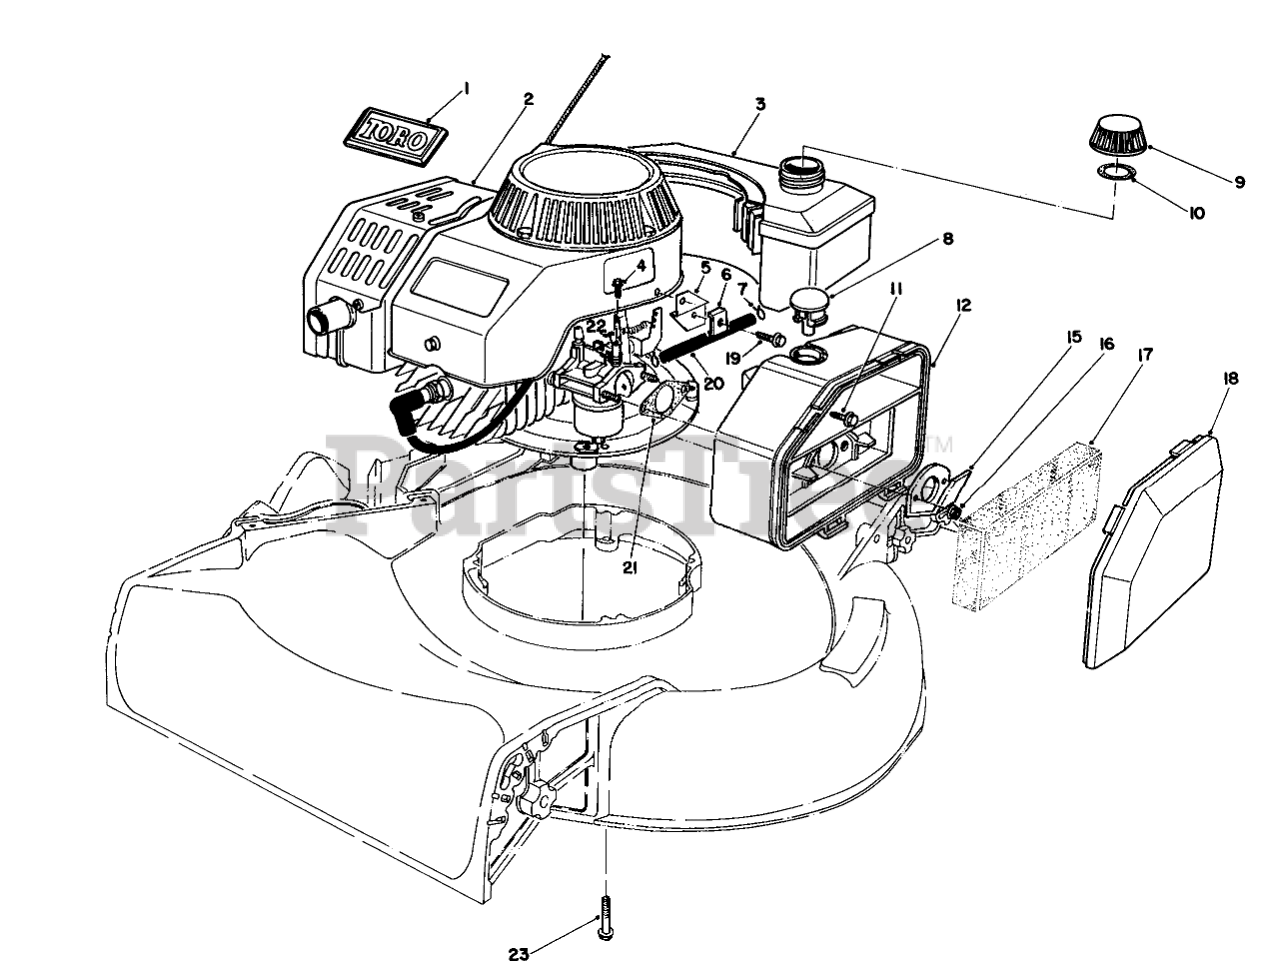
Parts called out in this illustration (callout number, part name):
1	TORO LOGO PLT
2	Engine (Incl. Ref. #1)
3	Fuel Tank Assembly
4	TAPPING SCREW
5	Carrier-Cable
6	CLAMP-CABLE
7	CLAMP-HOSE
8	Plug-Button
9	Gas Cap Assembly (Incl. Ref. #10)
10	GAS CAP GASKET
11	Screw-Hex Head
12	AIR CLEANER
15	SPIT BACK DEFLECTOR
16	M6 X 1 LOCKNUT
17	FILTER
18	AIR CLEANER COVER
19	Screw
20	FUEL LINE
21	GASKET-AIR CLEANER
22	CHOKE LEVER
23	FLG SCREW,3/8-16X2.000
